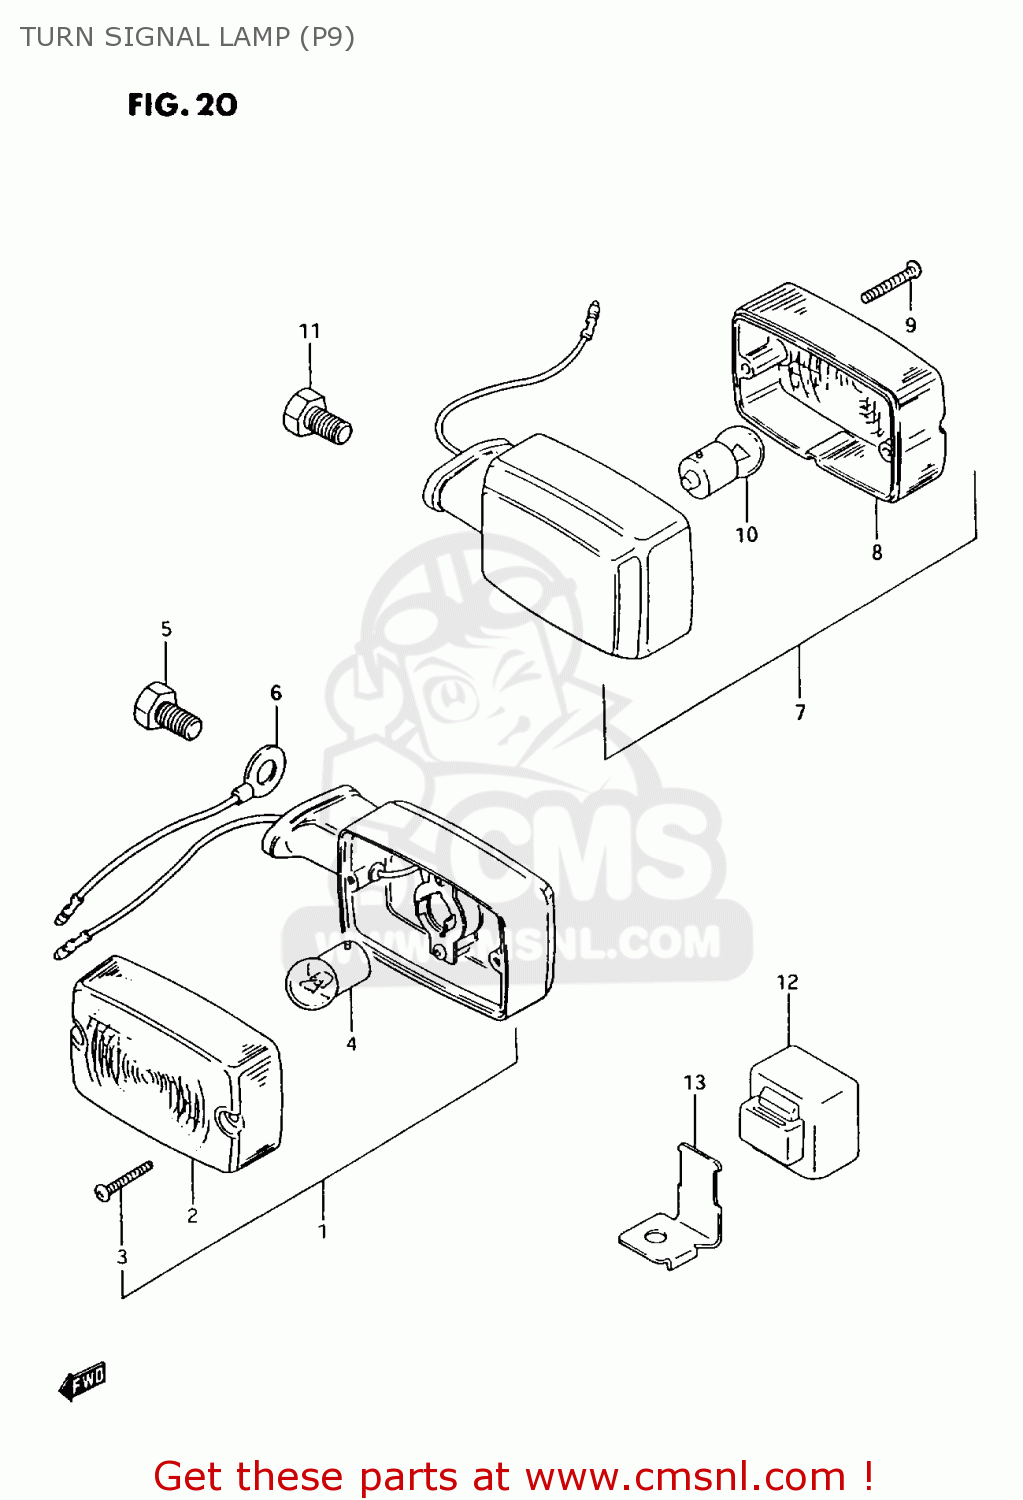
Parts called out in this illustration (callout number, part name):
1	LAMP ASSY, FRONT TURNSIGNAL RH
2	LENS
3	SCREW
4	BULB(6V8W,STANLEY,A4115)
5	BOLT, UPPER
6	LEAD WIRE,EARTH
7	LAMP ASSY, REAR TURNSIGNAL RH
8	LENS
9	SCREW
10	BULB(6V8W,STANLEY,A4115)
11	BOLT, UPPER
12	RELAY,TURN SIGNAL
13	BRACKET,TURN SIGNAL RELAY
